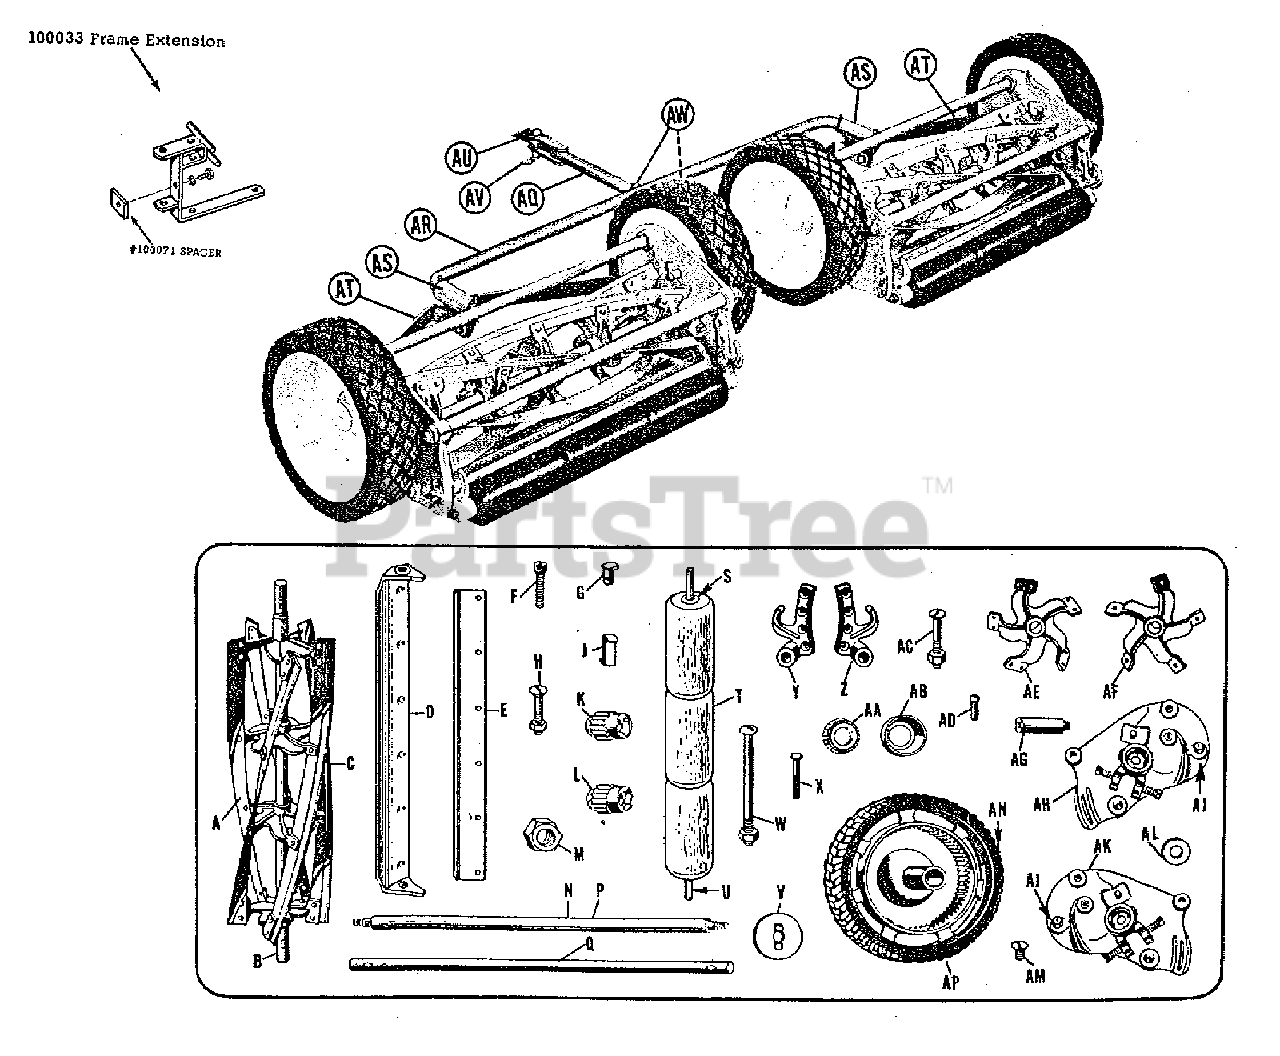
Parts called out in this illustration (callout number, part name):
A	Cylinder Knife 21"
B	Cylinder Shaft, 21", 11/16" dia x 26 1/8" lg.
C	CYLINDER ASSEMBLY, Less Bearings or Spacer
D	Cast Back, less Stationary blade 21"
D	Cast Back, complete with blade assembled
E	Steel Stationary Blade, 21"
F	SET SCREW, to Regulate Cast Back
G	Oil cup, for side plate
H	BOLT AND NUT, For Roller Bracket, 1/4" x 1-1/8"
J	Steel Pawl, 3/8" wide (both alike)
K	left Hand Pinion, 11/16" hole, 11 teeth
L	Right Hand Pinion, 11/16" hole, 11 teeth
M	Nut for end of front frame shaft
N	Front Frame Shaft
P	Rear Frame Shaft
Q	Cylinder Shaft, 21", 11/16" dia x 26 1/8" lg.
S	SPACING, Washer for sectional roller
T	Sectional Wood Roller 2-7/16" x 6-9/16" (1/2" hole)
U	Roller Shaft 21" (7/16" x 22-13/16")
V	Wheel Washer, for side plate (2 lugs)
W	Wheel Bolt and Nut 5/16" x 3 1/4"
X	SPRING LOCK PIN, To attatch cylinder end to cylinder shaft
Y	LEFT HAND ROLLER, Bracket
Z	RIGHT HAND ROLLER, Bracket
AA	Precision Taper Cylinder Bearing
AB	BEARING CUP, For side plate (less bearings)
AC	Cast Back Bolt and Nut
AD	RIVETS, For cylinder knives (1 set)
AE	Cylinder End (both alike)
AF	Cylinder Rings (all alike)
AG	Steel Wheel Stud 7/8" x 2-25/32"
AH	Left Hand Side Plate with stud
AJ	BOLT AND NUT, For tow bracket
AK	Right Hand Side Plate with stud
AL	FLAT WASHING, For roller bracket bolt and side plate towing bolt
AM	Machine screw for stationary blade, 1/4" x 3/8" flat head
AN	RUBBER TIRE, 3" Wide for Wheel 2645-W
AP	WHEEL, With tire PM-51-WW-D assembled
AP	Wheel only, less tire
AQ	CARB CLEANER-8OZ
AR	Bar, Draw Assembly, Double
AS	DEGREASER-15OZ
AT	BAR, Draw, Single
AU	OIL-4 CYCLE30W 48OZ
AV	Clip, Spring
AW	COLLAR, Set, 7/8
